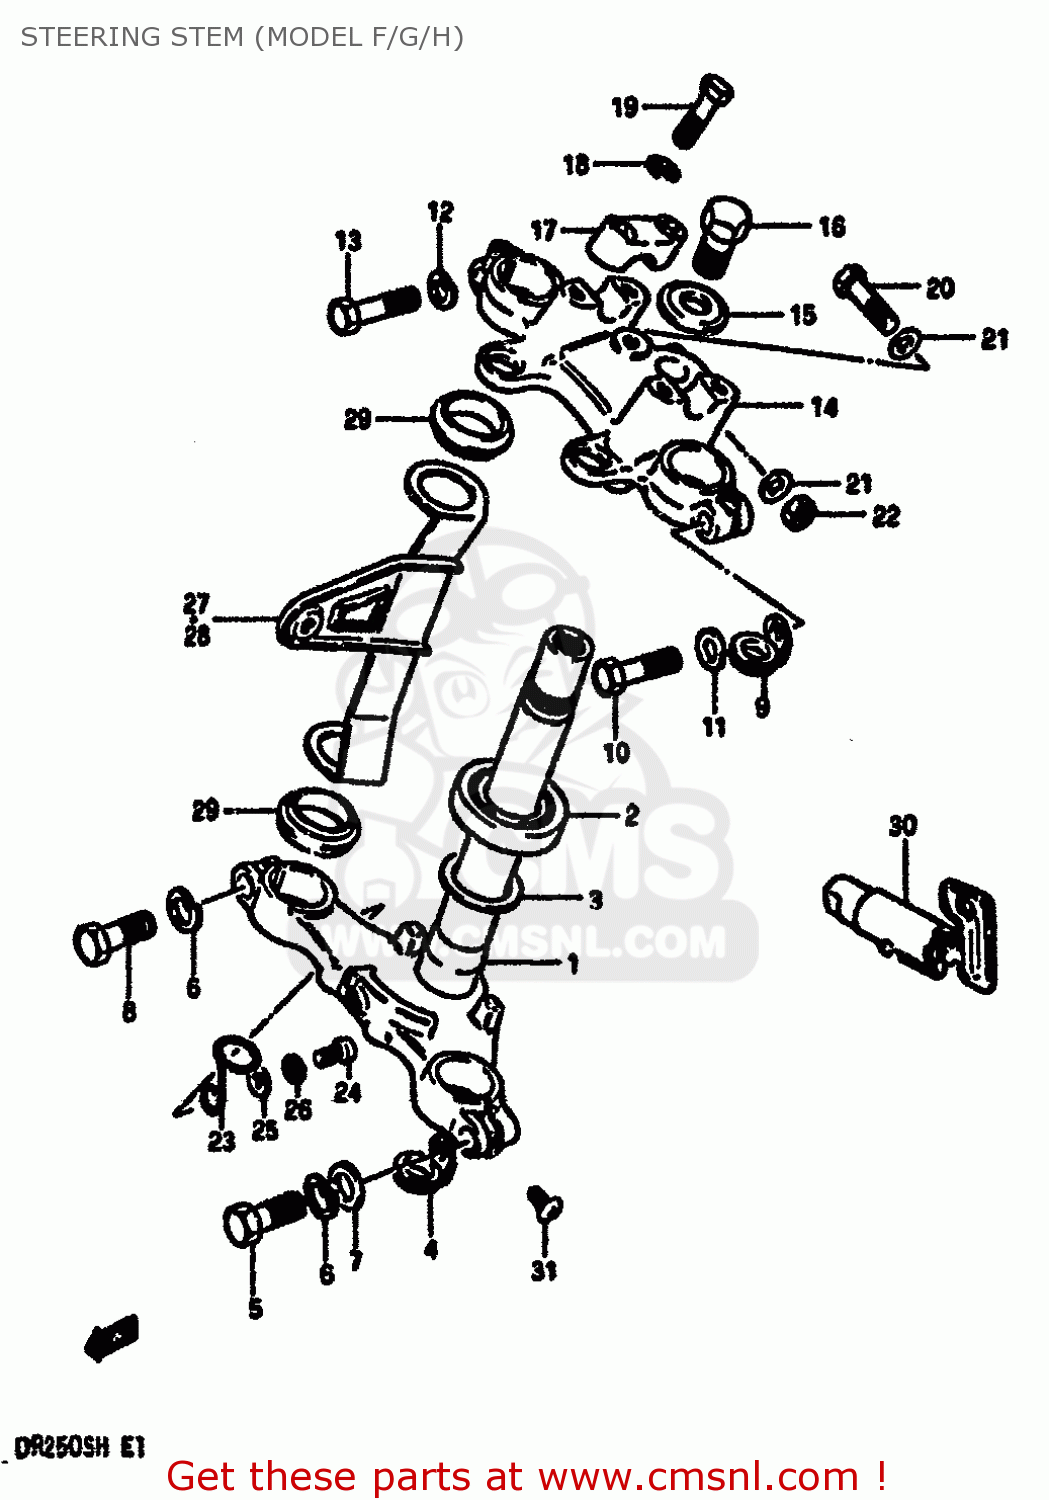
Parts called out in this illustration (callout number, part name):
1	STEERING STEM (GOLD)
2	BEARING
3	WASHER,THRUST
4	CLIP
5	BOLT 12X45
6	WASHER,LOCK 12
7	WASHER
8	BOLT
9	CLIP
10	BOLT 10X40
11	WASHER
12	WASHER,LOCK,10
13	BOLT,FORK INNER TUBE F
14	HEAD,STEERING STEM
15	WASHER
16	BOLT,STEERING STEM HEAD
17	HOLDER,HANDLEBAR
18	LOCK WASHER
19	BOLT
20	BOLT 8X50
21	WASHER
22	NUT
23	CLIP
24	SCREW
25	WASHER
26	WASHER,LOCK
27	BRACKET,HEARLAMP RH (BLACK)
28	BRACKET,HEADLAMP RH (BLACK)
29	GASKET
30	LOCK ASSY,STEERING(NEIMAN)
31	SCREW 5X6
